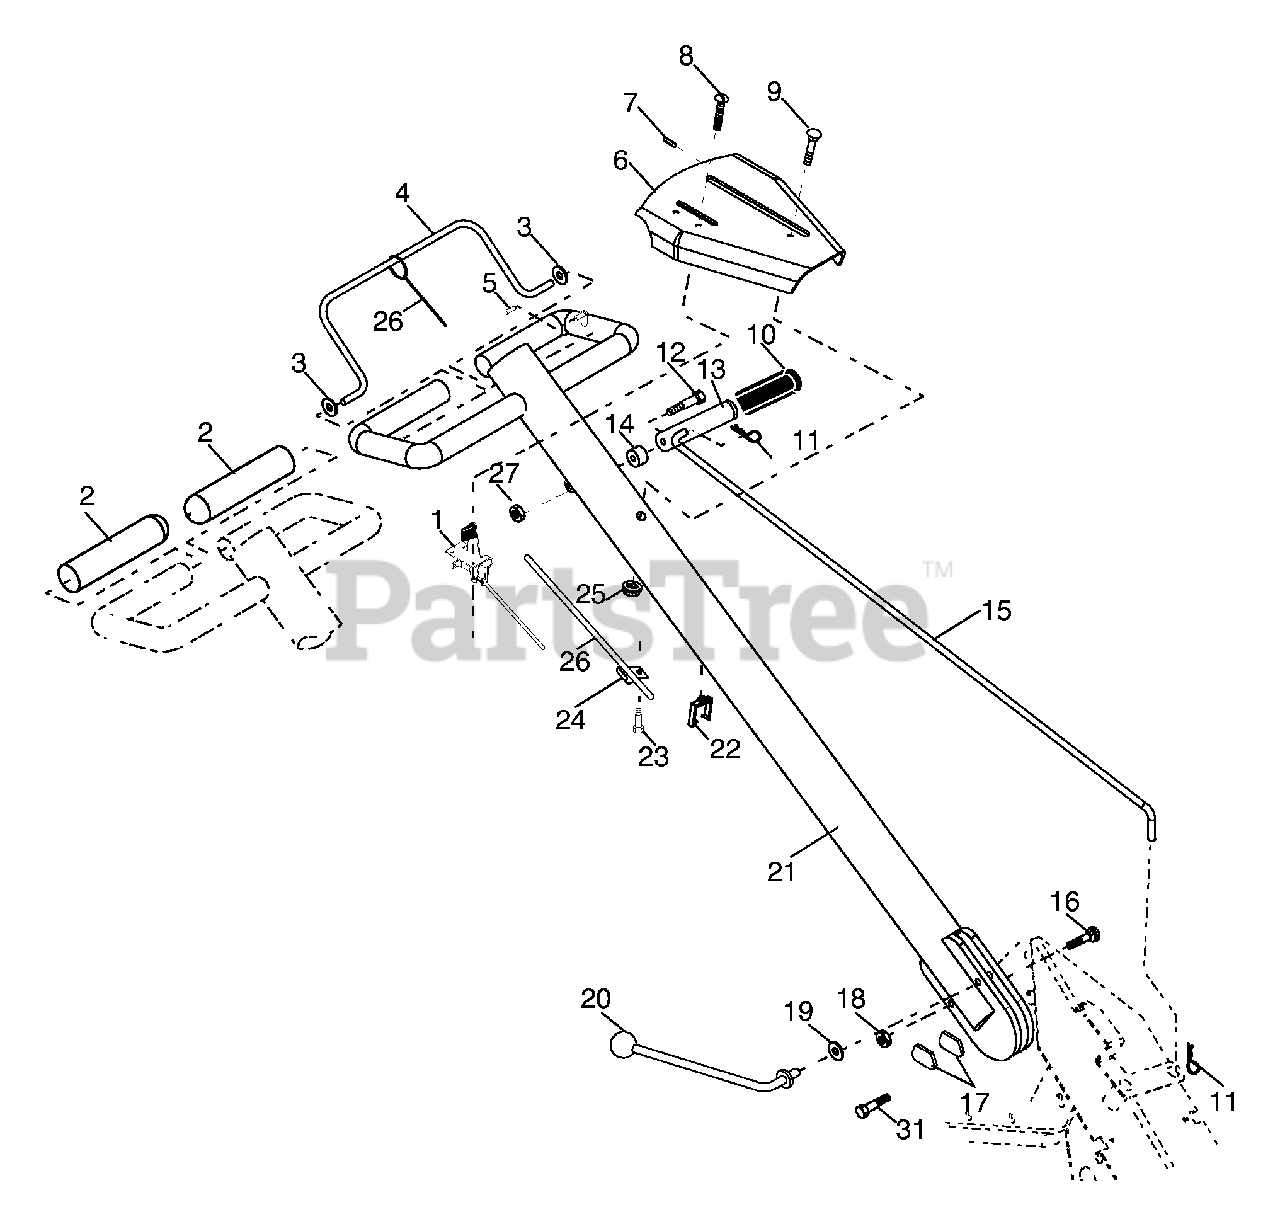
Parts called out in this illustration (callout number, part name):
1	Throttle, Control
2	Grip, Handle
3	Grommet, Handle
4	Bar, Drive Control Assembly
5	Cap, Vinyl
6	Panel, Control
7	Bushing, Split
8	Screw, Thd Cut 1/4-20 x 1/2
9	Bolt, 5/16-18 x 2-1/2
10	Handle, Grip
11	Retainer Spring
12	Bolt, Shoulder
13	Handle, Shift
14	Grommet, Rubber
15	Rod, Shift
16	Bolt 3/8-16 x 1 Gr. 5
17	Lock, Handle
18	Nut, Crownlock 3/8-16
19	Washer 13/32 x 1 x 11 Ga.
20	Lever, Lock, Handle
21	Handle, Assembly
22	Clip, Plastic, Cable
23	Screw, Hex, Washer Hd, Slotted #10-24 x 1/2
24	Clip
25	Locknut, Hex, Flange
26	Clutch, Cable
27	Nut, Lock 1/4-20
31	Bolt, Pivot
